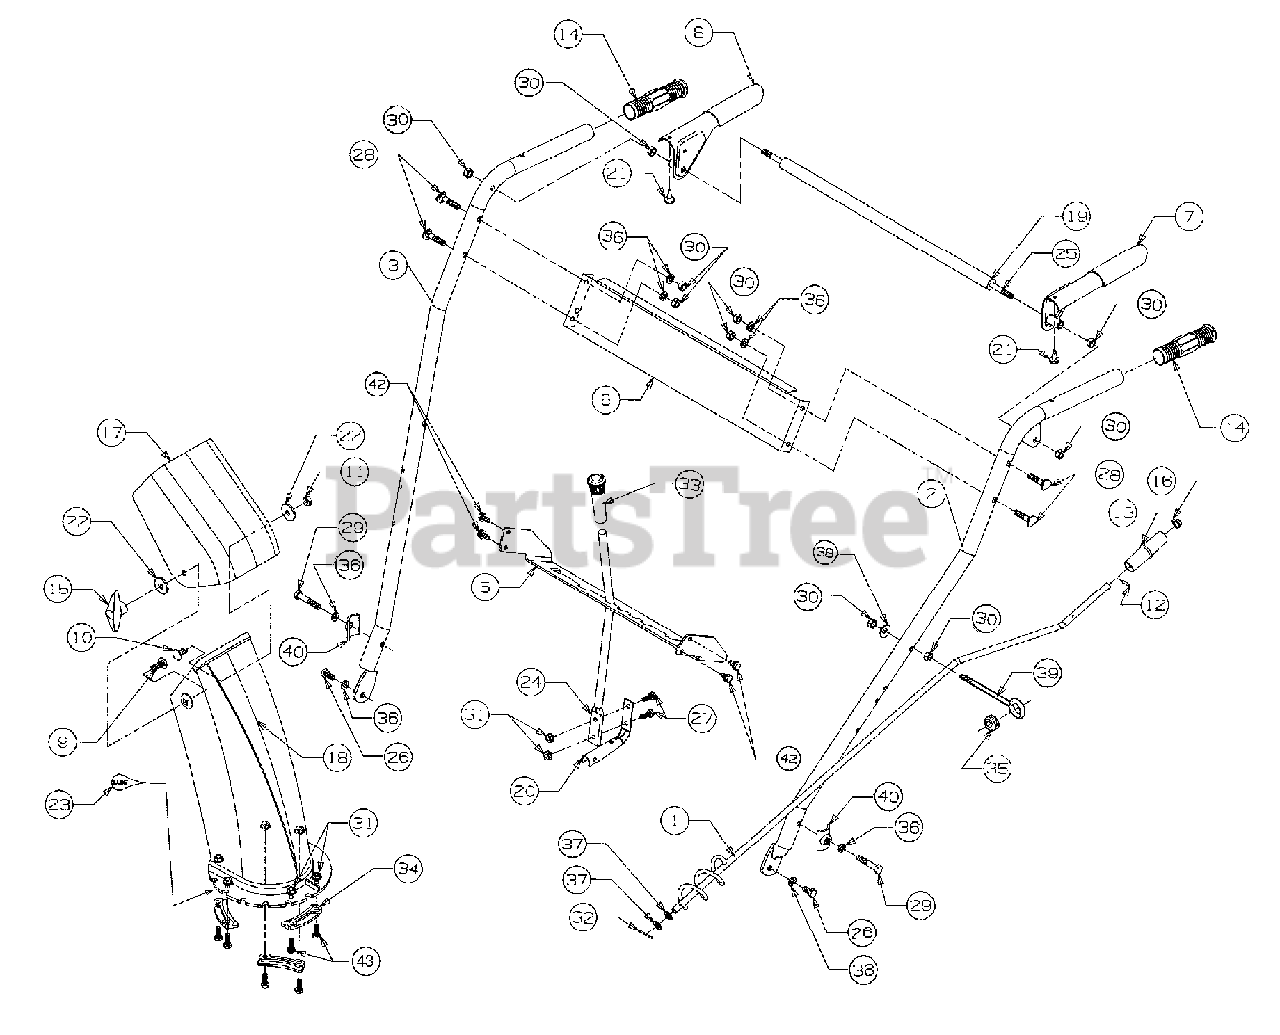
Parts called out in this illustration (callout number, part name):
1	Crank-Chute
8	Lever-Clutch-R.H.
9	Screw-Carriage
10	Screw-Carriage
11	Nut-Lock
12	Pin-Roll
13	Knob-Chute Crank
14	Grip - 5" Lg.
16	Cap-Push
17	Chute-Upper
18	Chute-Lower
19	Tube-Pivot Rod Cover
20	Spring-Shift Lever
21	Bumper
22	Washer
25	Rod-Pivot
26	Screw
27	Screw
28	Screw
29	Screw
30	Nut-Hex
31	Nut-Hex Flange
32	Pin-Cotter
33	Grip-Shift Lever
34	Keeper-Chute
35	Grommet
36	Washer-Lock
37	Washer-Flat
38	Washer-Bell
39	Eyebolt
40	Tab-Handle
42	Screw
43	Screw
